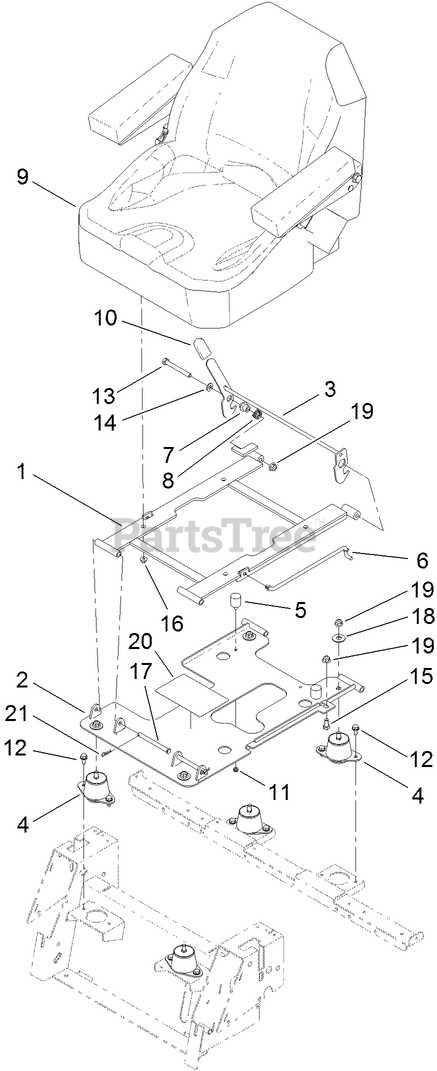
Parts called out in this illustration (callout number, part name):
1	SEAT PAN ASM
2	SEAT BASE ASM
3	LATCH ASM
4	ISOLATOR-SEAT
5	BUMPER
6	ROD-PROP
7	BUSHING-LATCH, SEAT
8	SPRING-TORSION
9	SEAT ASM
10	GRIP-LEVER
11	NUT-LOCK, NI
12	SCREW-HWHTF
13	SCREW-HH
14	WASHER-FLAT
15	SCREW-HH
16	NUT-HF, NI
17	PIN-CLEVIS
18	WASHER-FLAT
19	NUT-HF, NI
20	DECAL-MAINTENANCE
21	PIN-COTTER
